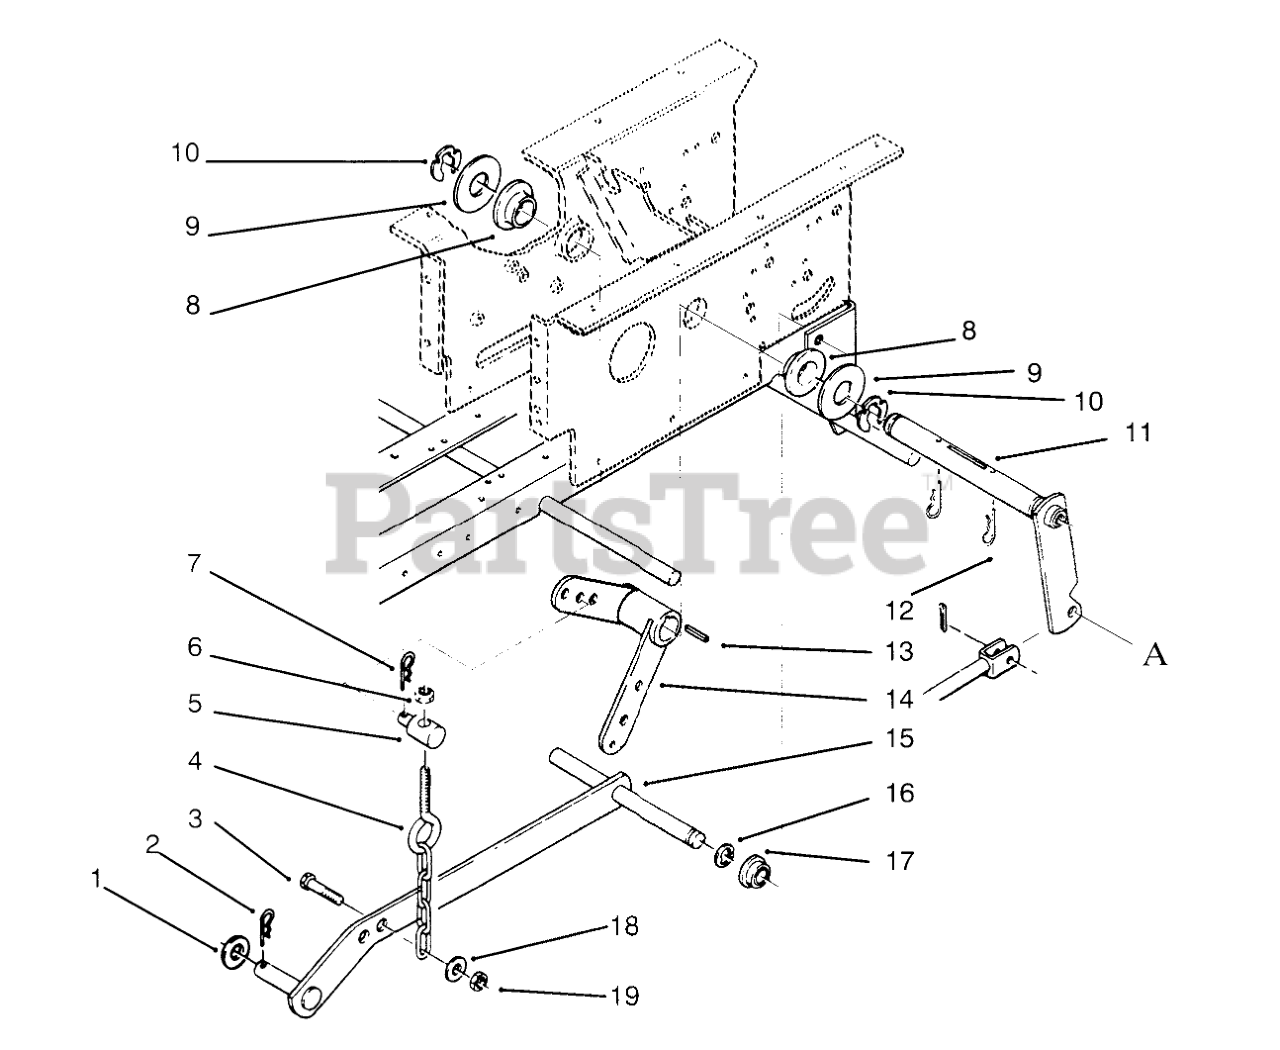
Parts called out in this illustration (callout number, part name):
1	WASHER-FLAT
2	PIN-HAIR
3	SCREW-HH
4	CHAIN-LIFT
5	TRUNNION-LIFT
6	NUT-LOCK, NI
7	PIN-HAIR
8	BEARING-FLANGE
9	WASHER-FLAT
10	RING-RETAINING
11	WLDMT-LIFT ARM
12	PIN-HAIR
13	KEY-SQUARE
14	LIFT LEVER ASM
15	Bar-Lift
16	RING-RETAINING, EXTERNAL
17	BUSHING
18	WASHER-PLAIN
19	NUT-LOCK, NI
